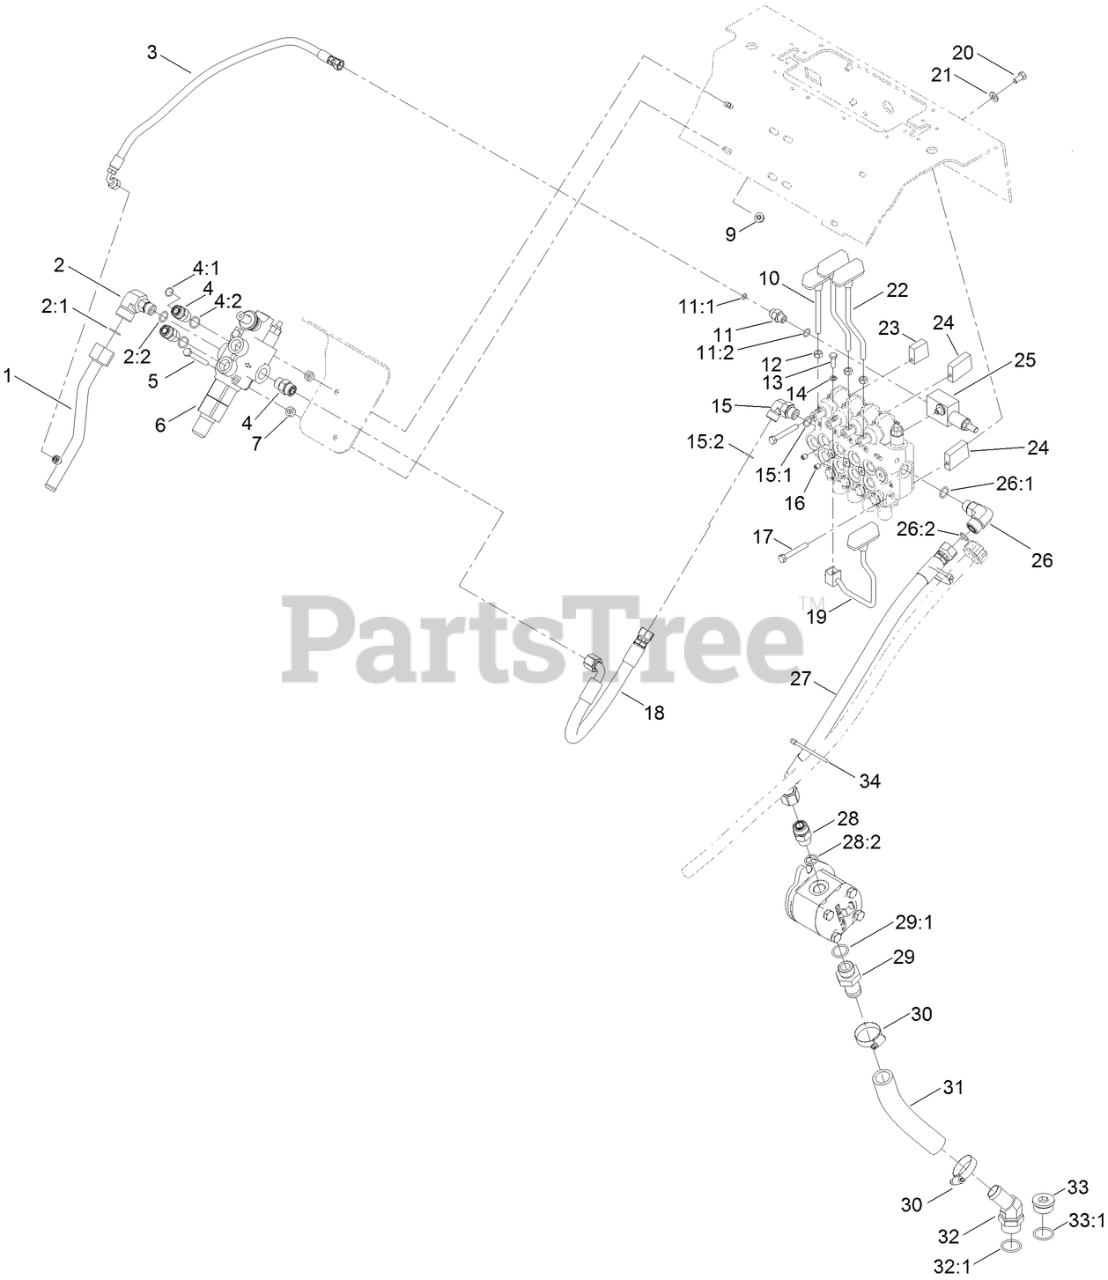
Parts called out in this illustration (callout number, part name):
1	HYDRAULIC TUBE ASM
2	FITTING-ELBOW, 90 DEG
2:1	O-RING
2:2	O-RING
3	HYD HOSE ASM
4	FITTING-STRAIGHT
4:1	O-RING
4:2	O-RING
5	SCREW-HH
6	VALVE-HYD, AUXILIARY
7	SPACER
9	NUT-HF, NI
10	LEVER-CYLINDER
11	FITTING-STRAIGHT
11:1	O-RING
11:2	O-RING
12	NUT-HEX
13	SCREW-HH
14	WASHER-LOCK
15	FITTING-ELBOW, 90 DEG
15:1	O-RING
15:2	O-RING
16	SCREW-SET, HSH
17	SCREW-HH
18	HYD HOSE ASM
19	LEVER-CONTROL
20	SCREW-HH
21	WASHER-PLAIN
22	LEVER-DRIVE
23	SPACER-UPPER V
24	SPACER V
25	RELIEF VALVE ASM
26	FITTING-ELBOW, 90 DEG
27	HYD HOSE ASM
28	FITTING-STRAIGHT
29	FITTING
29:1	O-RING
32	FITTING-ELBOW-45
32:1	O-RING
33	FITTING-PLUG
33:1	O-RING
34	TIE-CABLE
